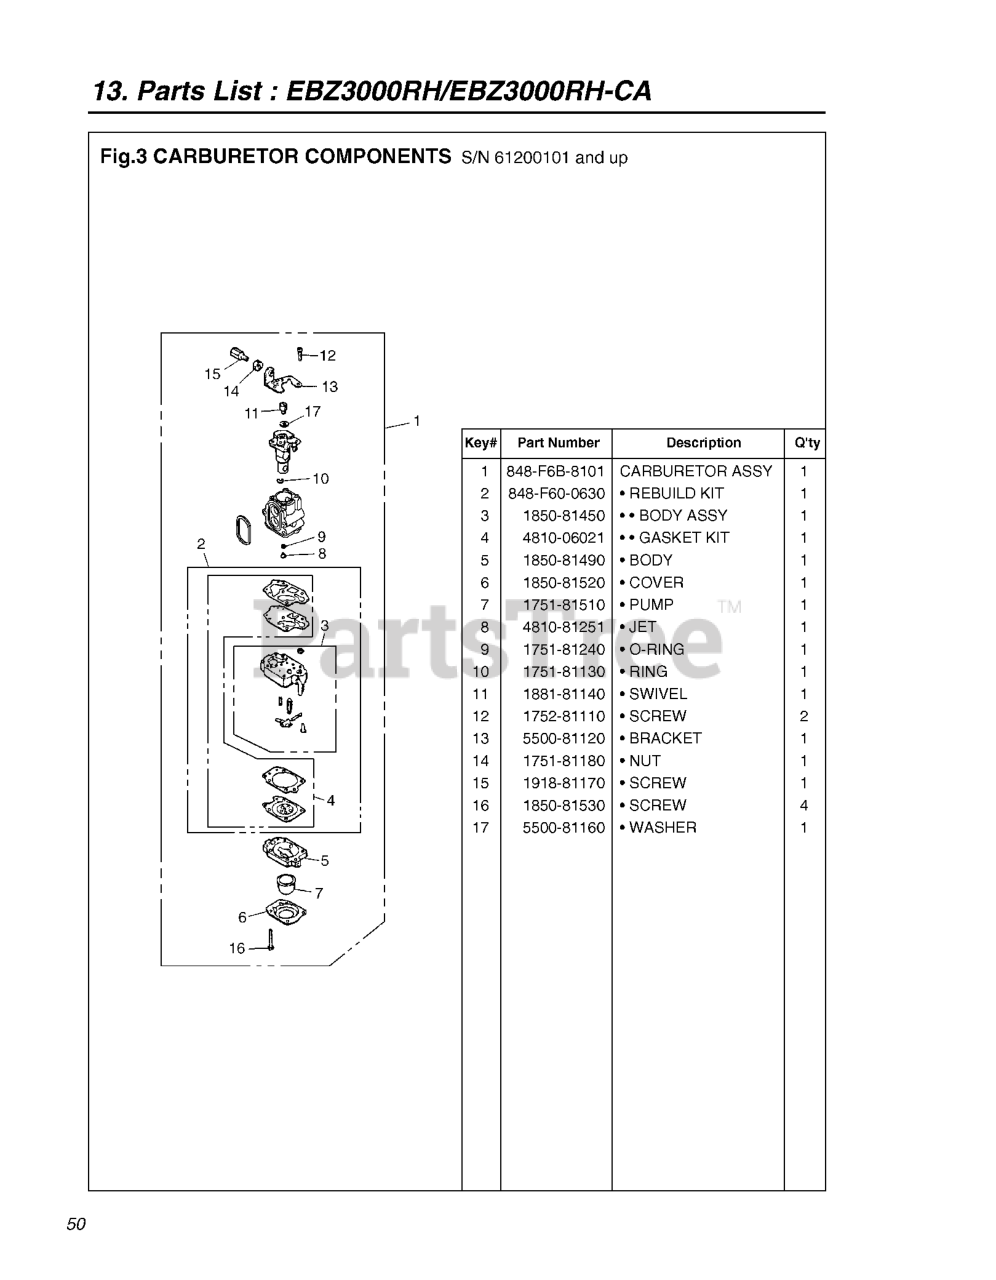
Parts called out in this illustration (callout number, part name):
1	CARBURETOR A
2	REBUILD KIT
3	CARBURETOR BODY
4	GASKET KIT
6	1OVER
10	RING
11	SWIVEL
12	SCREW
13	BRACKET
14	NUT
15	ADJUSTER
17	WASHER
